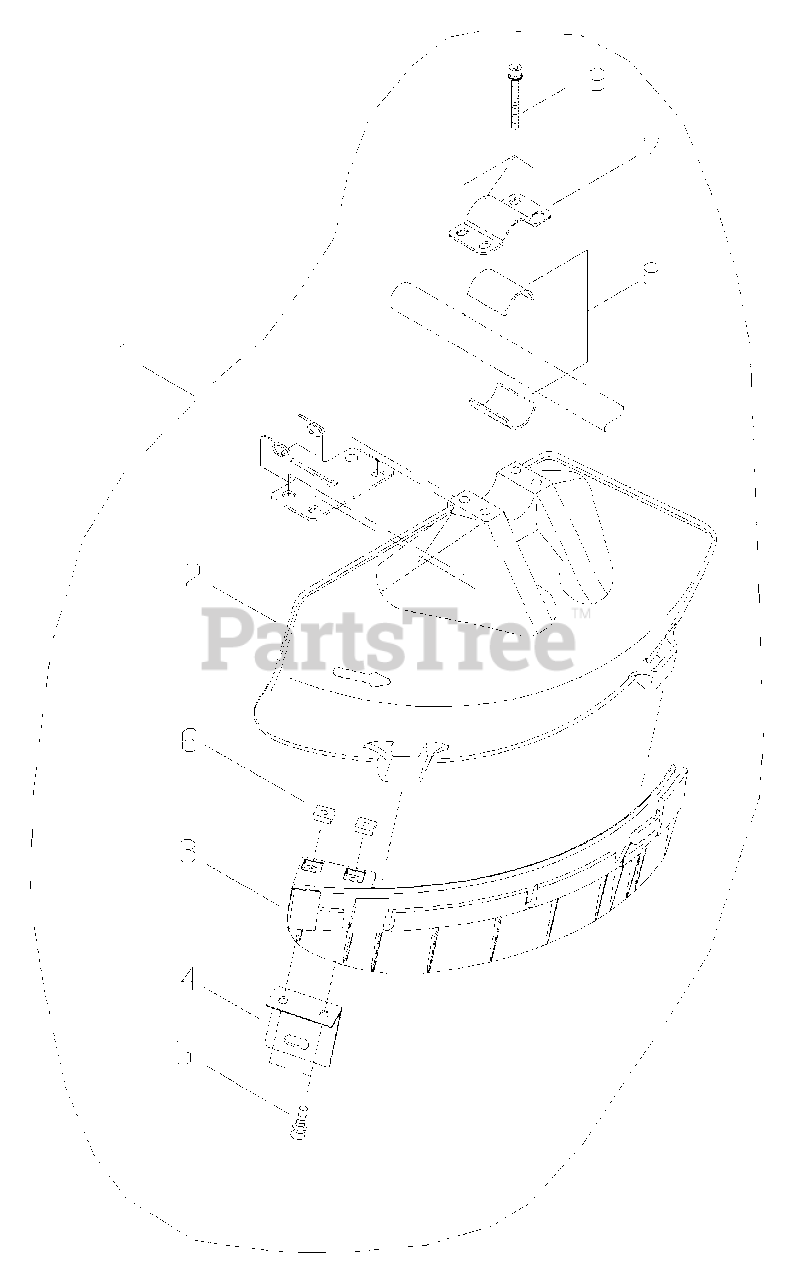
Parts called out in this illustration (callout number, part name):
1	DEBRIS SHIELD KIT
2	SHIELD, DEBRIS
3	SHIELD, DEBRIS
4	KNIFE, TRIMMER LINE
5	SCREW - 5X16
6	NUT - 5
7	CLAMP - UPPER
8	SPACER
9	SCREW - 5X45
